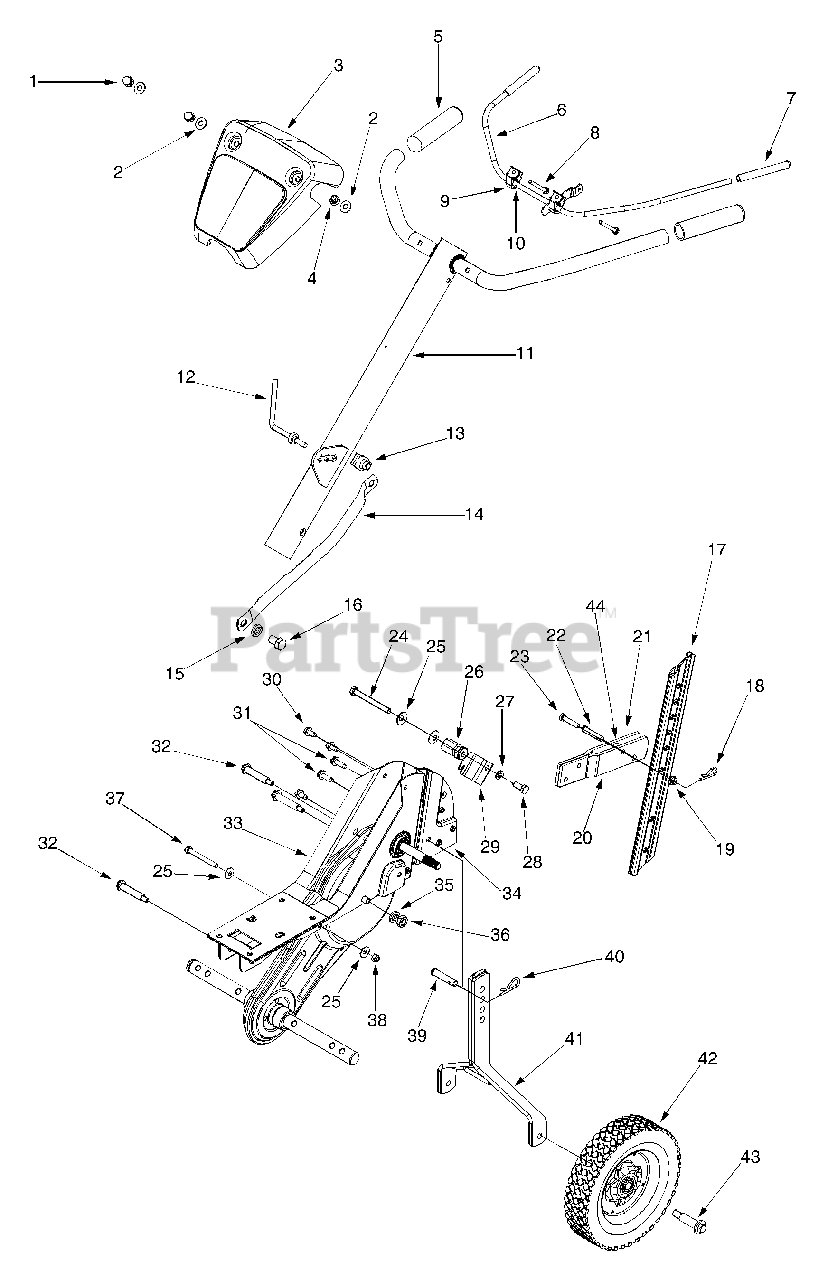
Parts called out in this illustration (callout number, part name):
1	Acorn Lock Nut 1/4-20
2	Flat Washer .271" I.D. x .630" O.D.
3	Handle Cover
4	Hex Nut 1/4-20 Gr.2
8	Hex Bolt 1/4-20 x 2.25" Lg. Gr.5
9	Clutch Handle Holder
10	Flat Washer .385" I.D. x .62" O.D.
13	U Nut 5/16-18
16	Hex Bolt 1/2-20 Gr. 5
19	Hex Flange L-Nut 5/16-18
23	Hex Bolt 5/16-18 x 1.5" Lg.
24	Hex Bolt 5/16-18 x 3" Lg.
25	Wash. Bell. .340" I.D. x .872" O.D.
26	Spec. Hex Nut
27	L-Wash. 5/16" I.D.
28	Hex Bolt 5/16-18 Gr. 5
30	Hex Wash Screw 5/16-18 x .62"
31	Hex Wash. Hd. TT-Tap Scr.
32	Shdl. Bolt 5/16-18
35	Lock Washer 7/16
36	Jam Nut 7/16-20 Gr. 2
37	Hex Bolt 5/16-18 x 2.75" Lg.
38	Hex Nut 5/16-18 Thd.
42	Wheel Ass'y 8" x 1.75"
43	Shoulder Screw .496 x 1.445
